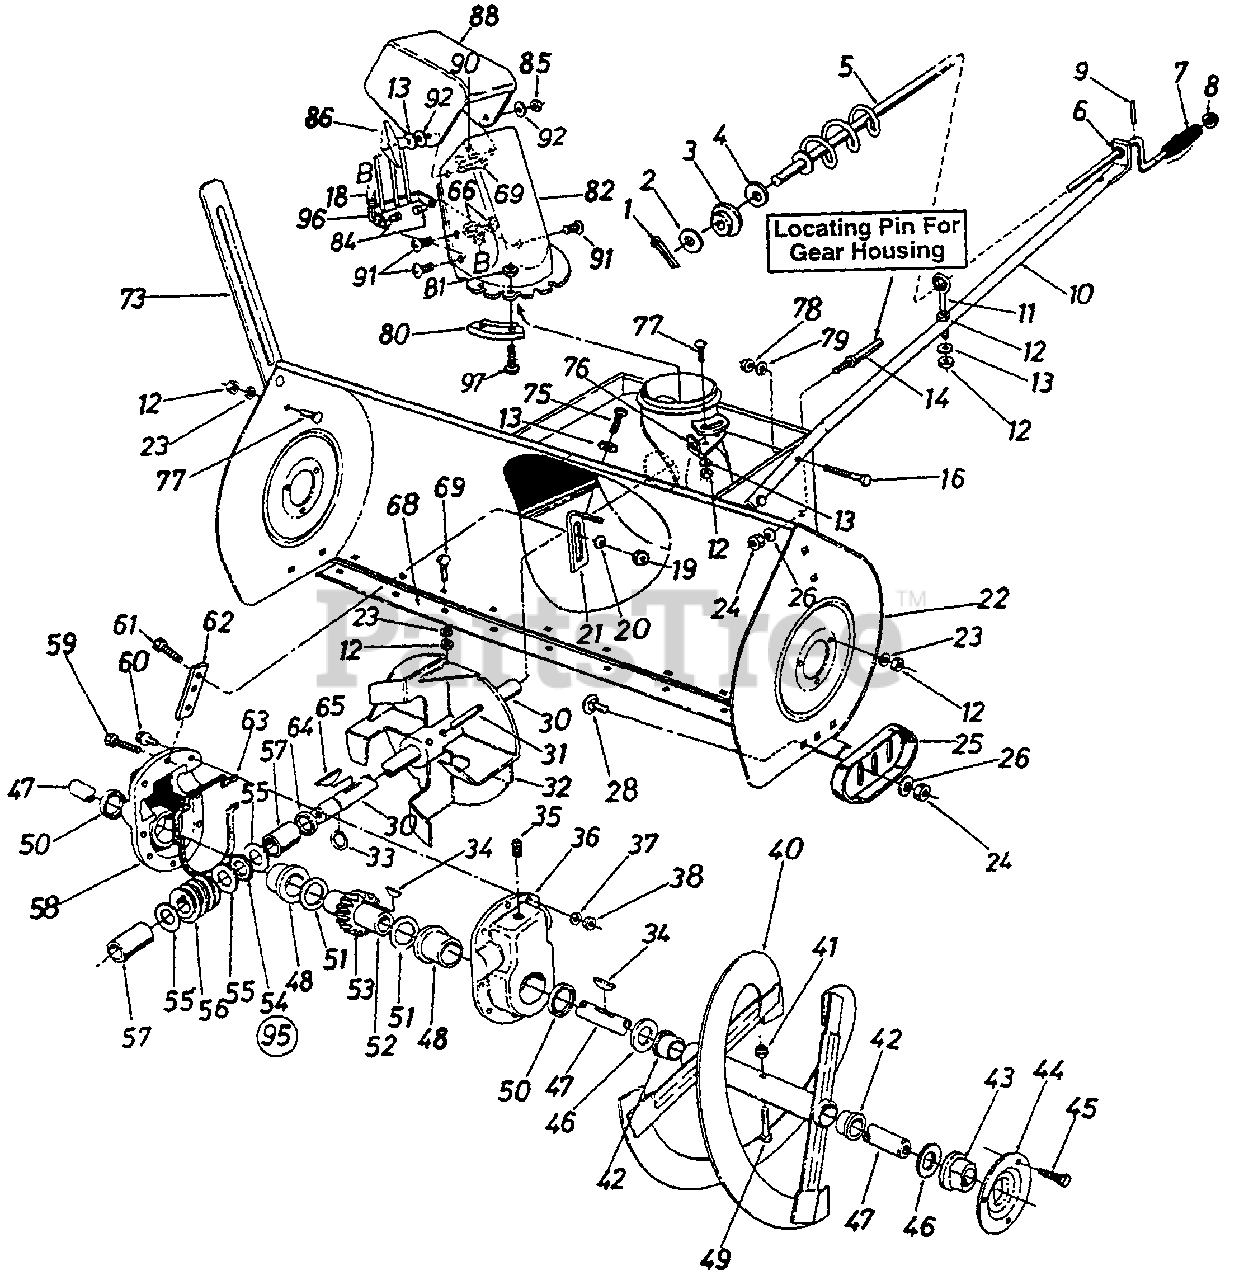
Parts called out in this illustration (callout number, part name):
1	Cotter Pin 3/32" x .75"
2	Fl-Wash .385" I.D. x .62" O.D. x .06"
3	Plastic Bushing .380" I.D.
4	Fl-Wash .385" I.D. x.62" O.D. x .06
5	Chute Crank Ass'y.
6	Plastic Bushing .38" I.D.
7	Knob - Black
8	Cap Speed Nut 3/8" Rod
9	Spring Pin
10	Chute Crank Supporting Tube
11	Eyebolt Chute Crank Support
12	Hex Nut 5/16-18 Thd.
13	Bell-Wash .345" I.D. x .88" O.D. x .06"
14	Belt Keeper Studs 3/8-16 x 2.75"
16	Hex Bolt 3/8-24 x 1.25" Lg.
18	Extension Spring
19	Hex Nut 1/4-28 Thd.
20	Bell-Wash .25" I.D. x.88" O.D. x .062"
22	45" Snow Thrower Hsg. Ass'y.
23	L-Wash. 5/16" I.D.
24	Hex Jam Nut 3/8-16 Thd.
25	Reversible Slide Shoe
26	Bell-Wash .4" I.D. x.88" O.D. x .06"
28	Carr. Bolt 3/8-16 x.62" Lg.
30	Blower Axle 14.75" Lg.
31	Spr. Spiral Pin - H.D.
34	#91 Woodruff Key 1/4" x 3/4" Dia.
35	Plastic Vented Plug 1/4-18 Pipe Thd.
36	Gear Hsg. Half - L.H.
37	Shakeproof Spr. Wash.
38	Hex Ins. L-Nut 5/16-18 Thd.
41	Hex ins. L-Nut 5/16-18 Thd.
42	Flange Bearing
43	Flange Bearing w/Flats
44	Bearing Housing
45	Hex Sems Bolt 5/16-18 x .75" Lg.
48	Flange Bearing
49	Shear Bolt 5/16-18 x 1.75
50	Oil Seal 1.5" I.D. Garlock
51	Fl-Wash. 1.5" I.D. x 2" O.D. x .03"
52	Worm Gear Shaft
53	Worm Wheel - L.H. Double Thd.
54	Thrust Brg .88" I.D. x 1.44" O,D. x .078"
55	Fl-Wash .88" I.D. x 1.4" O.D. x .125"
56	Worm Gear - L.H. Double Thd.
57	Sleeve Brg .875" I.D.
58	Gear Hsg. Half - R.H.
59	Hex Bolt 5/16-18 x 1.25" Lg.
60	Hex Bolt 5/16 x 1" Lg.
61	Hex Bolt 1/4-28 x .75" Lg.
62	Gear Hsg. Support Plate
63	Rubber Gasket
64	Oil Seal for .875" I.D. Garlock
65	#9 Hi-Pro Key 3/16" x 3/4 Dia.- H.T.
66	Hex L-Nut 1/4-20 Thd.
69	Carr-Bolt 5/16-18 x 1" Lg.
75	Hex AB-Tap Scr. 5/16 x .75" Lg.
77	Carr. Bolt 5/16-18 x .75" Lg.
78	Hex Nut 3/8-24 Thd.
79	L-Wash. 3/8" I.D.
80	Chute Flange Keeper
81	Hex Flange L-Nut 1/4-20 Thd.
82	Lower Chute
84	Shld. Nut 1/4-20 Thd.
85	Hex L-Nut 5/16-18 Thd.
86	Hand Knob
88	Upper Chute
90	Truss Mach. Scr. 5/16-18 x .75" Lg.
91	Truss Mach. Scr. 1/4-20 x .5" Lg.
92	Fl-Wash .344" I.D. x 1.125 O.D. x .125"
96	Truss Mach. Scr. 1/4-20 x 3/4" Lg.
97	Hex Bolt 1/4-20 x .75" Lg.
